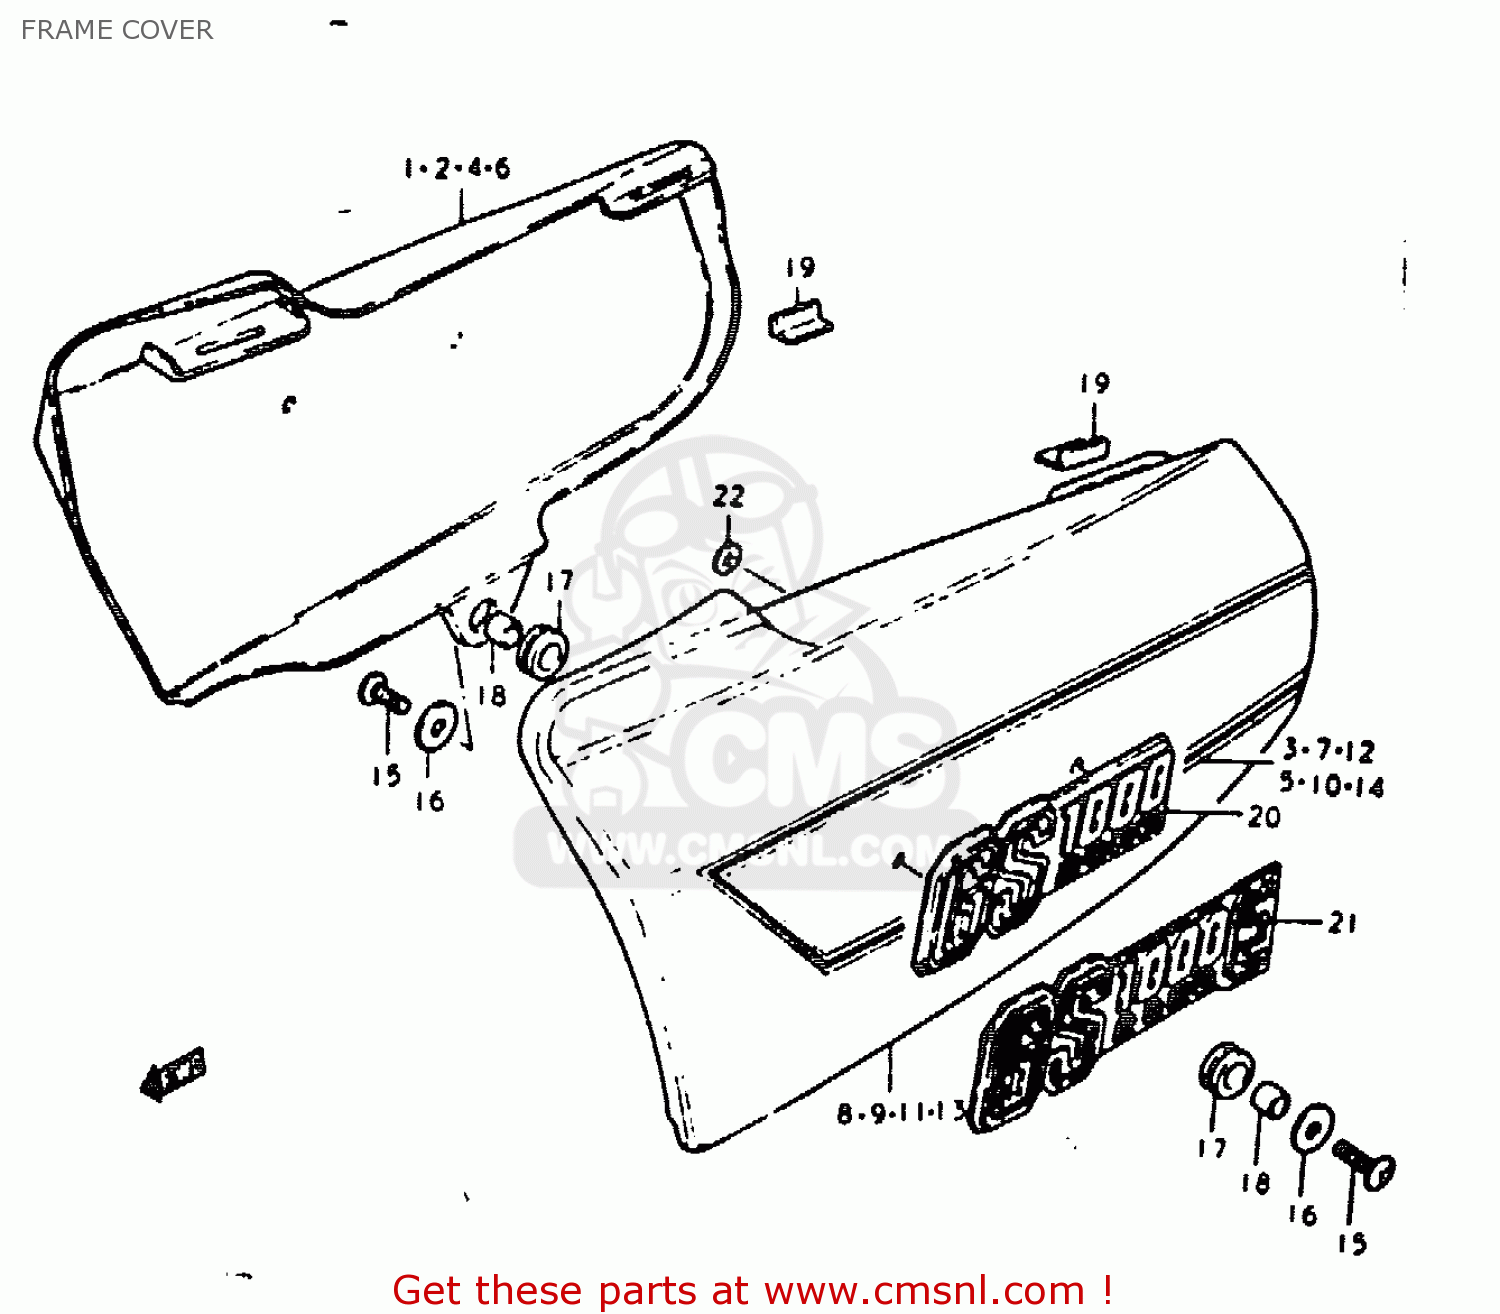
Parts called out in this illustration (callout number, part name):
1	COVER,FRAME,RIGHT
8	COVER,FRAME,LEFT
15	SCREW (6X20)
16	WASHER (6.5X18X1.6)
17	CUSHION
18	SPACER (6.8X10X10)
19	CUSHION,FRAME COVER
20	EMBLEM
22	NUT
